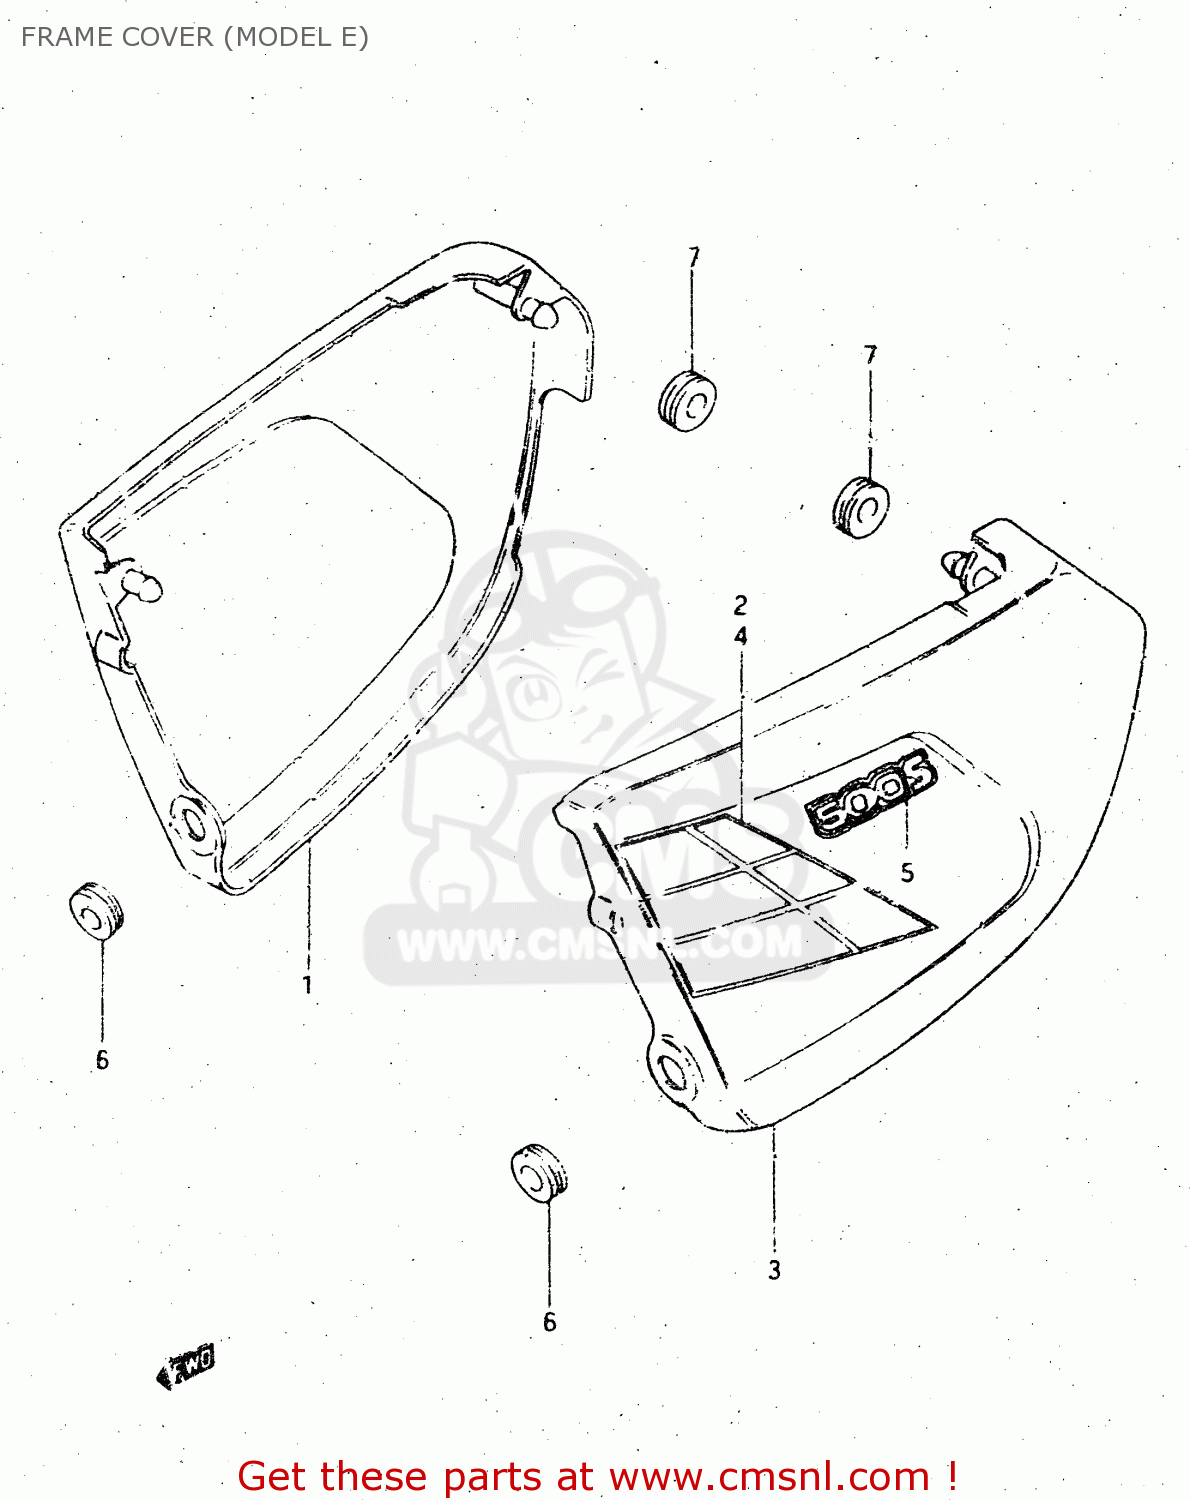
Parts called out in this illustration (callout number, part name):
1	COVER,FRAME,RIGHT
2	TAPE SET, FRAME COVER RH
3	COVER,FRAME,LEFT
4	TAPE SET, FRAME COVER LH
5	EMBLEM, FRAME COVER
6	CUSHION
7	CUSHION
